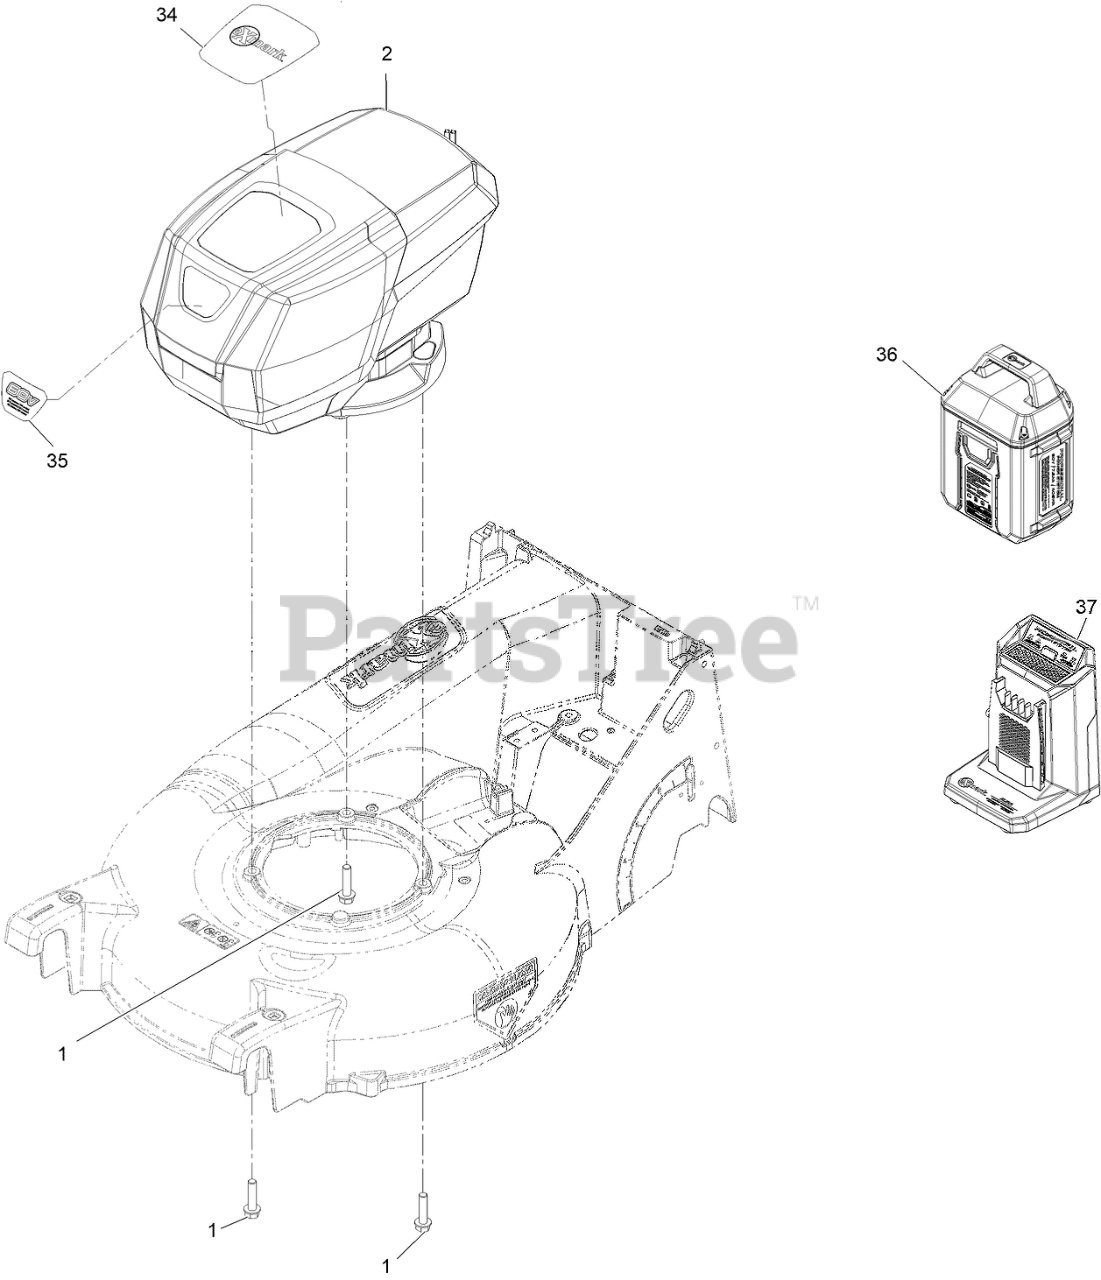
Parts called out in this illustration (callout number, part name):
1	SCREW-HWH
2	MOTOR MODULE
34	DECAL-HOOD,TOP
35	DECAL-HOOD,FRONT
36	BATTERY-405WH
37	CHARGER-RAPID
